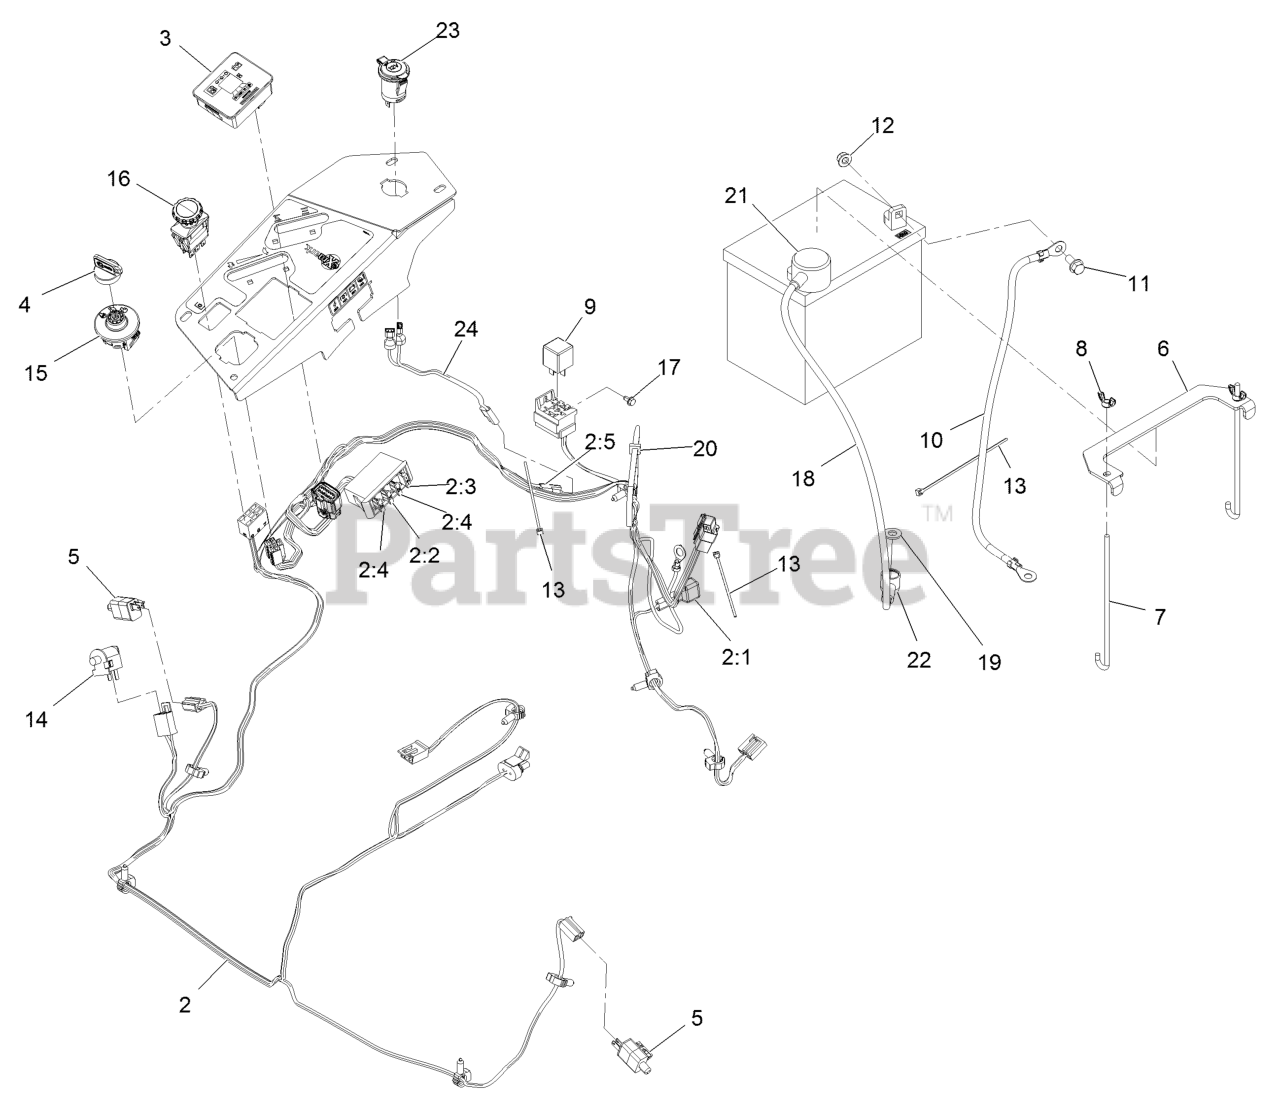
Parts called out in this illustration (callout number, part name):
2	Harness-Wire, Main
2:2	Fuse-Blade, 10 Amp
2:3	Fuse-Blade, 15 Amp
2:4	Fuse-Blade, 25 Amp
2:5	Cap-Plug
3	Fuel/Hour Meter ASM
4	Key-Ignition
4	Key-Exmark Logo
6	Strap-Tie Down, Battery
7	Bolt-Holddown
8	Wingnut-Nyloc 1/4-20
9	Relay-12Vdc 40 Amp
10	Cable-Battery, Negative
11	Screw-HH Flg 5/16-18 X 3/4
12	Nut-Nyloc 5/16-18 Flg
13	Tie-Cable 5 1/2 (Small)
15	Switch-Ignition
16	Switch-PTO, 10 Amp
17	Screw-HWH #10-24 X 3/8
18	Cable-Battery, Positive
19	Washer-3/8 SAE
20	Tie-Cable 7 15/16 (Large)
21	Insulator-Battery
22	Insulator-Solenoid
23	Port-Power, 12V
24	Harness, Receptacle 12V
